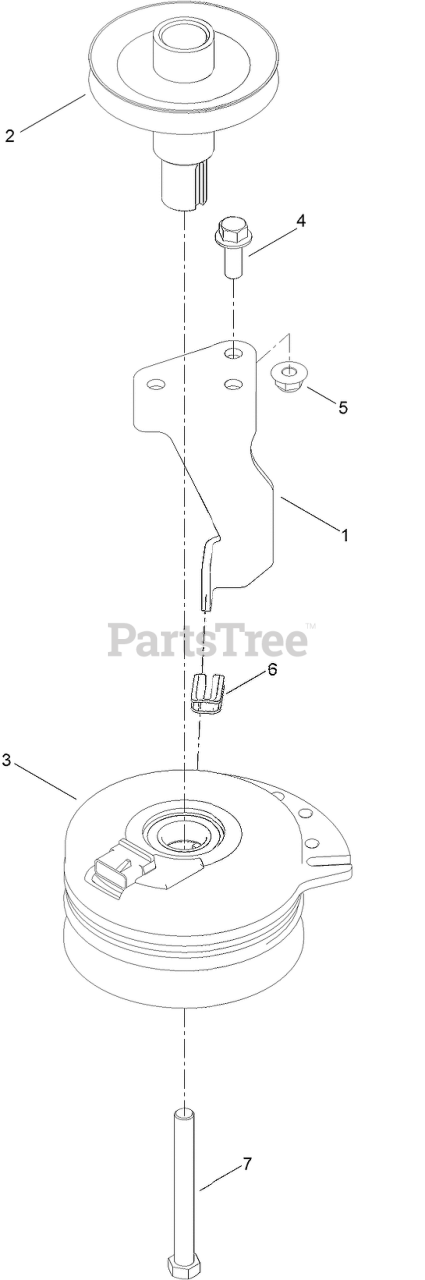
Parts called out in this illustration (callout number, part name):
1	STOP - CLUTCH (NARROW)
2	PULLEY-ENGINE
3	CLUTCH-ELECTRIC
4	SCREW-HHF
5	NUT-HF, NI
6	ISOLATOR-CLUTCH
7	SCREW-HH
